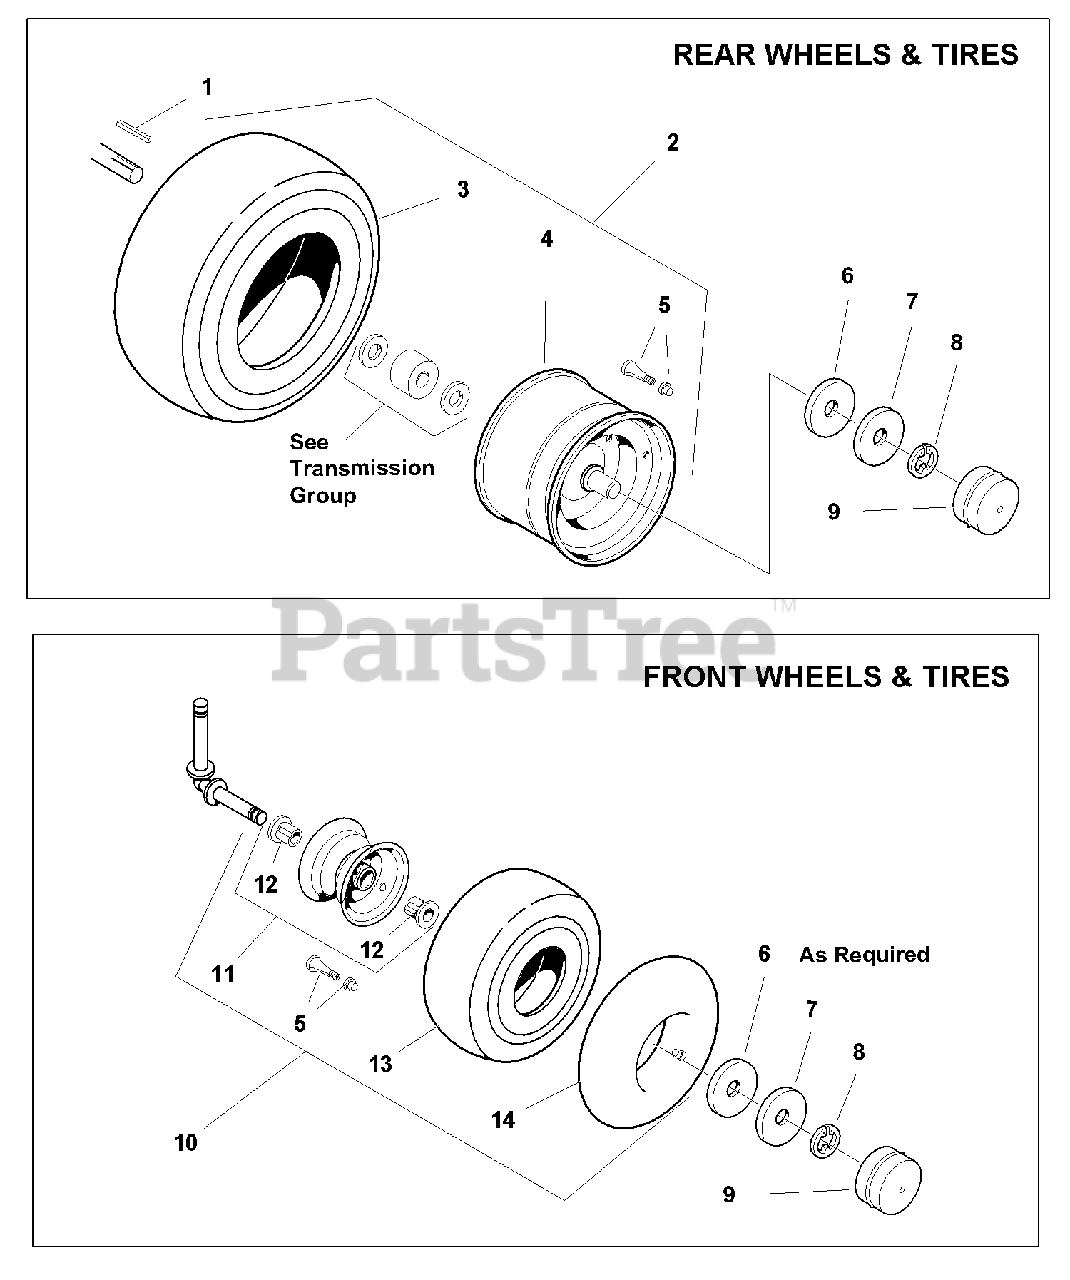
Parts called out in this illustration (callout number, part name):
1	KEY, 3/16 x 2
2	WHEEL & TIRE ASSEMBLY
3	TIRE, 18 X 8.50 Turf Saver II Carlisle
4	WHEEL, 7 X 8
5	VALVE STEM & CAP ASSEMBLY
10	WHEEL & TIRE ASSEMBLY (Includes Ref. Nos. 5, 11, 12, 13, & 14)
10	WHEEL & TIRE ASSEMBLY (Includes Ref. Nos. 5, 11, 12, 13, & 14) (Export)
11	WHEEL & BUSHINGS ASSEMBLY (Includes Ref. No. 12)
12	BEARING
13	TIRE, 15 X 6 Turf Saver II Carlisle
13	TIRE, 15 X 6.5 - 6 Super Trac II
